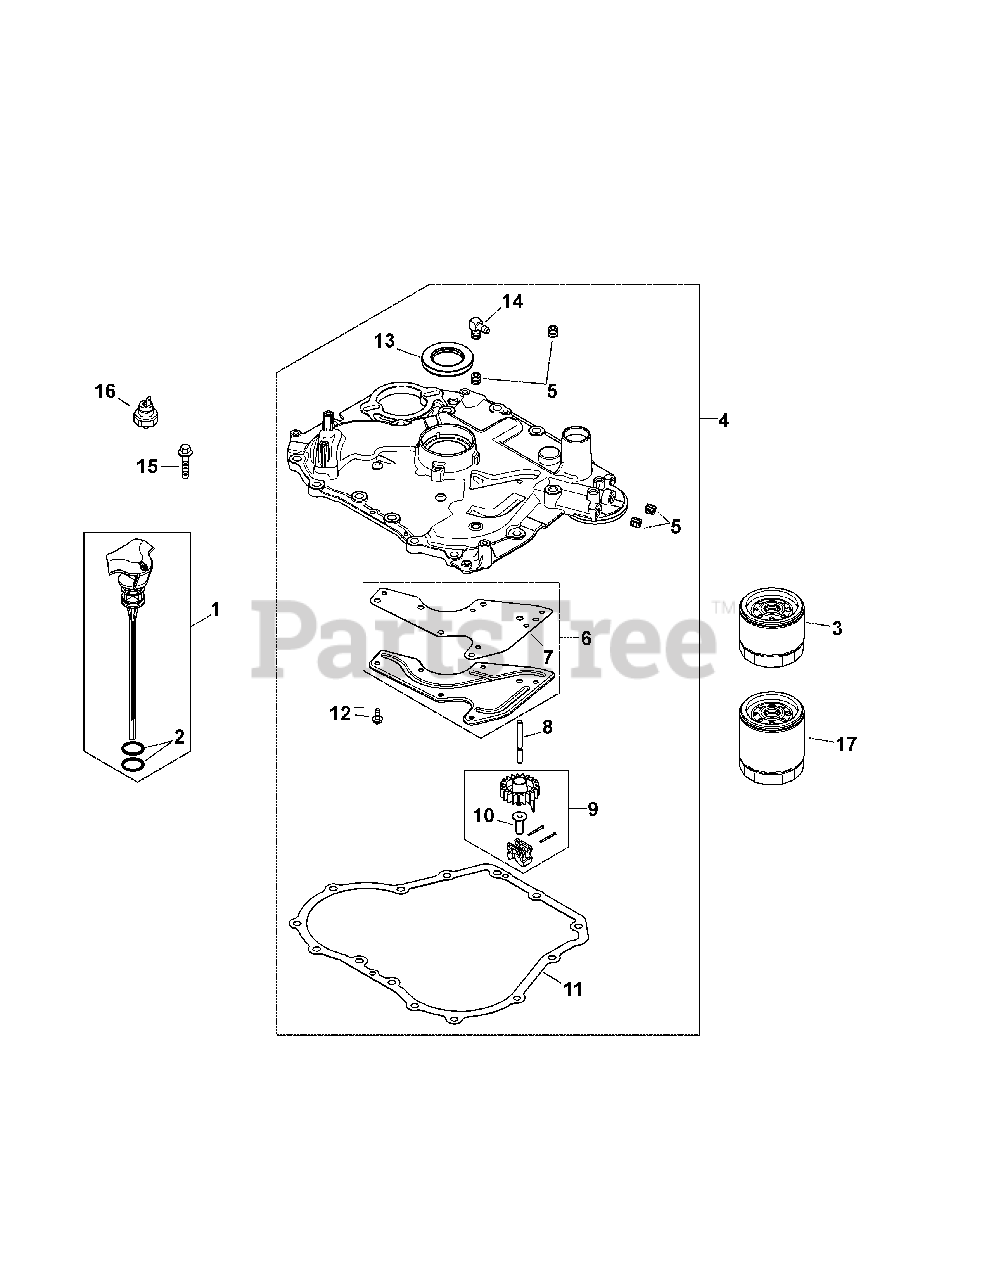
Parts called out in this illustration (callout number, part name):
1	Dipstick Assembly-Std Yellow
2	O-Ring
4	Closure Plate Assembly
5	Ctsk. Pipe Plug, 1/8
6	Oil Passage Cover Kit
7	Oil Passage Gasket
8	Governor Cross Shaft
9	Governor Gear Assembly
10	Governor Regulating Pin
11	Closure Plate Gasket
12	Flg. Thd. Frm. Screw, M5 X 0.8 X 13
13	Oil Seal
14	90° Hose Connector
15	Hex Flange Screw, 1/2
16	Fuse Block
17	Fuse Block
